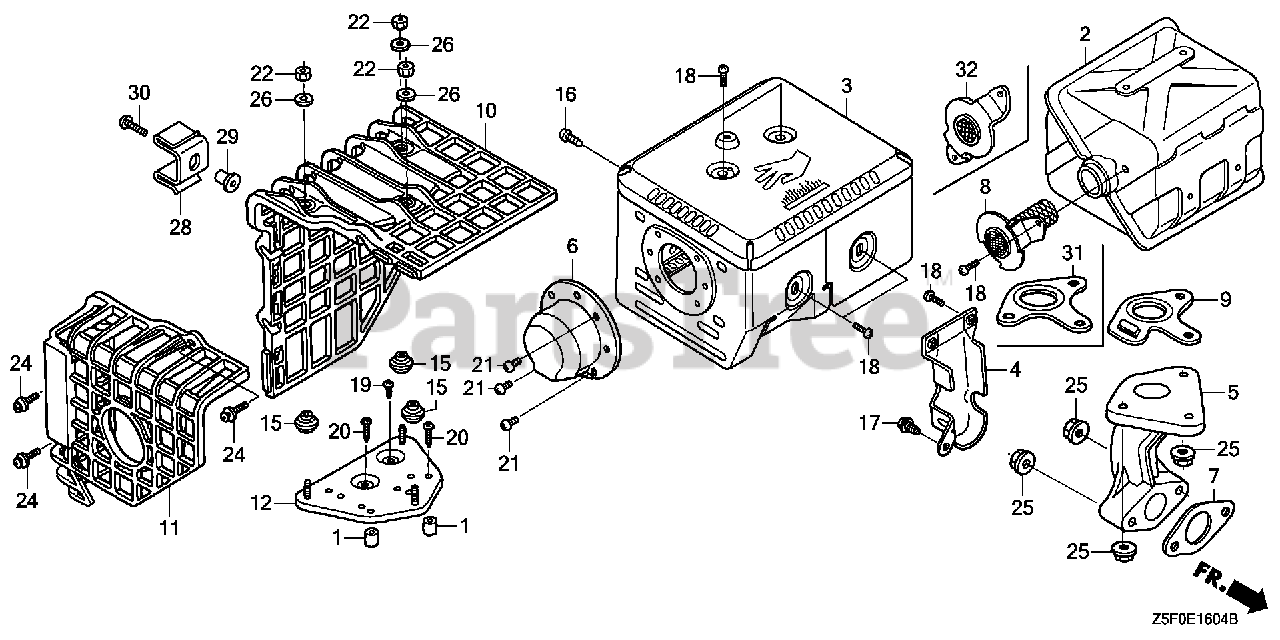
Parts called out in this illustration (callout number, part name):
2	MUFFLER
3	PROTECTOR, MUFFLER
7	GASKET, EX. PIPE
8	ARRESTER, SPARK
9	GASKET, MUFFLER (ARRESTER)
16	SCREW, TAPPING (6X10)
18	SCREW, TAPPING (5X8)
25	NUT, FLANGE (8MM)
